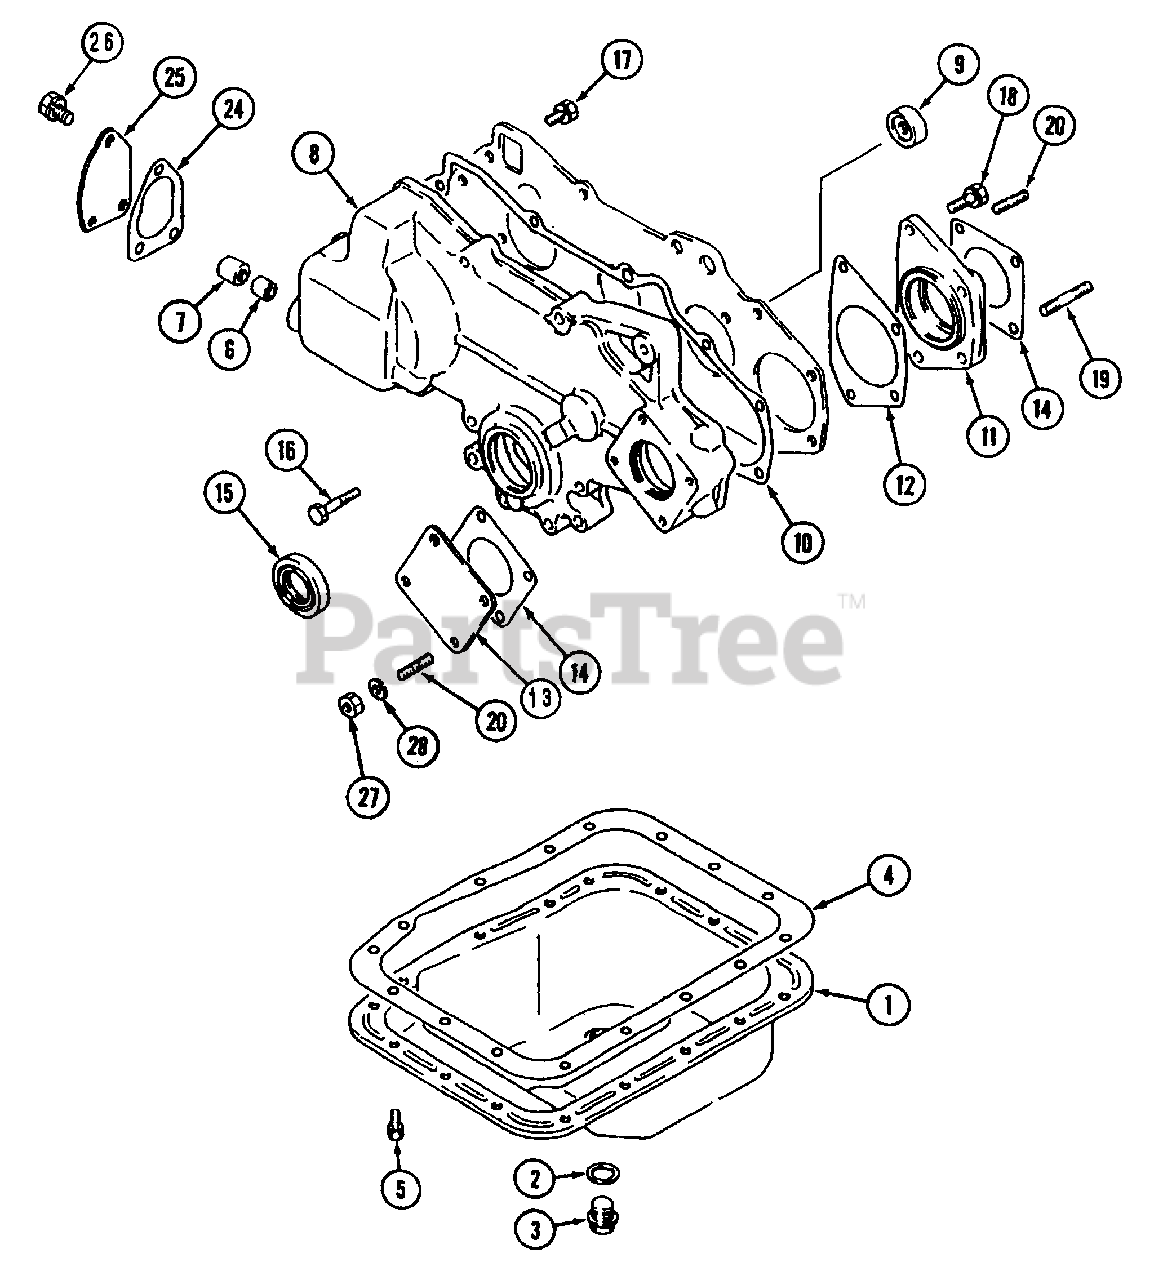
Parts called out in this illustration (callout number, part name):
1	Pan Ass'y., Oil
2	Gasket, Oil Drain Plug
3	Plug, Oil Drain
4	Gasket, Oil Pan
5	Bolt, W/Washer
6	Bearing, Needle
7	Bearing, Needle
9	Plug, Thrust
10	Gasket, Gear Case
11	Housing, Pump Gear Bearing
12	Gasket, Housing
13	Cover, Oil Pump
14	Gasket, Oil Pump Cover
17	Bolt, W/Washer
18	Bolt, W/Washer
24	Gasket, Governor Cover
25	Cover, Governor
26	Bolt, W/Washer
28	Washer, Spring
